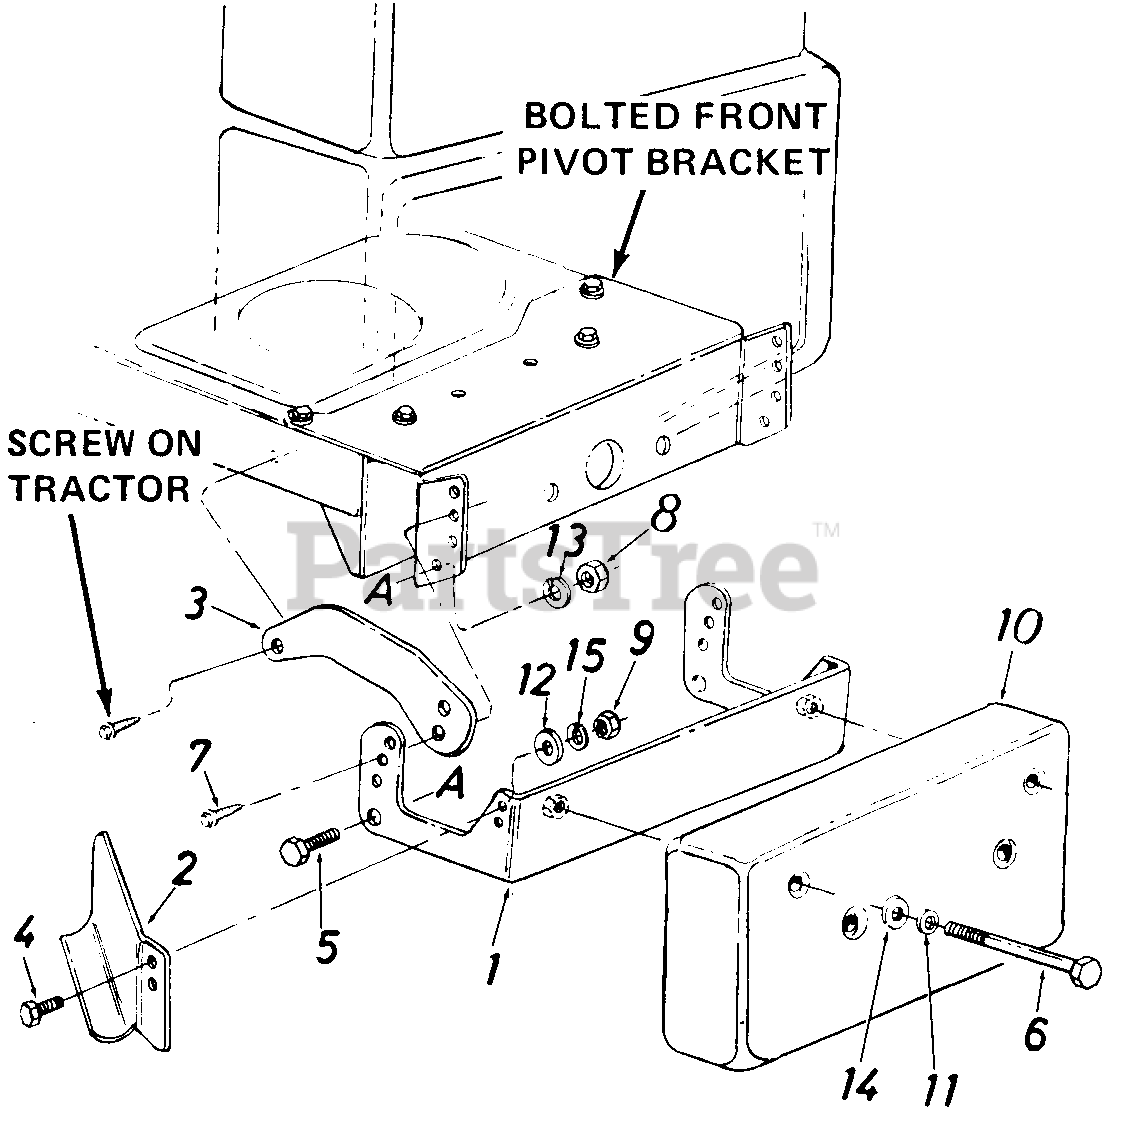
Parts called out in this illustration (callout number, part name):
1	Counterweight Bracket Ass'y.
2	Exhaust Deflector
3	Tie Strap
4	Hex Bolt 1/4-20 x .62" Lg.*
5	Hex Bolt 7/16-20 x 1.0" Lg.
6	Hex Bolt 3/8-16 x 4.5" Lg.
7	Hex AB Tap Scr. 5/16-18 x 1.0" Lg.
8	Hex Jam Nut 7/16-20 Thd.
9	Hex Nut 1/4-2 Thd.*
10	Front Counterweight-38 Lbs.
11	Bell-Wash..40" I.D. x.88" O.D.
12	Fl-Wash. .28" I.D. x .50" O.D.
13	L-Wash. 7/16" I.D.
14	Fl-Wash .39" I . D. x 1.12" O.D.
15	L-Wash. 1/4" I.D.*
